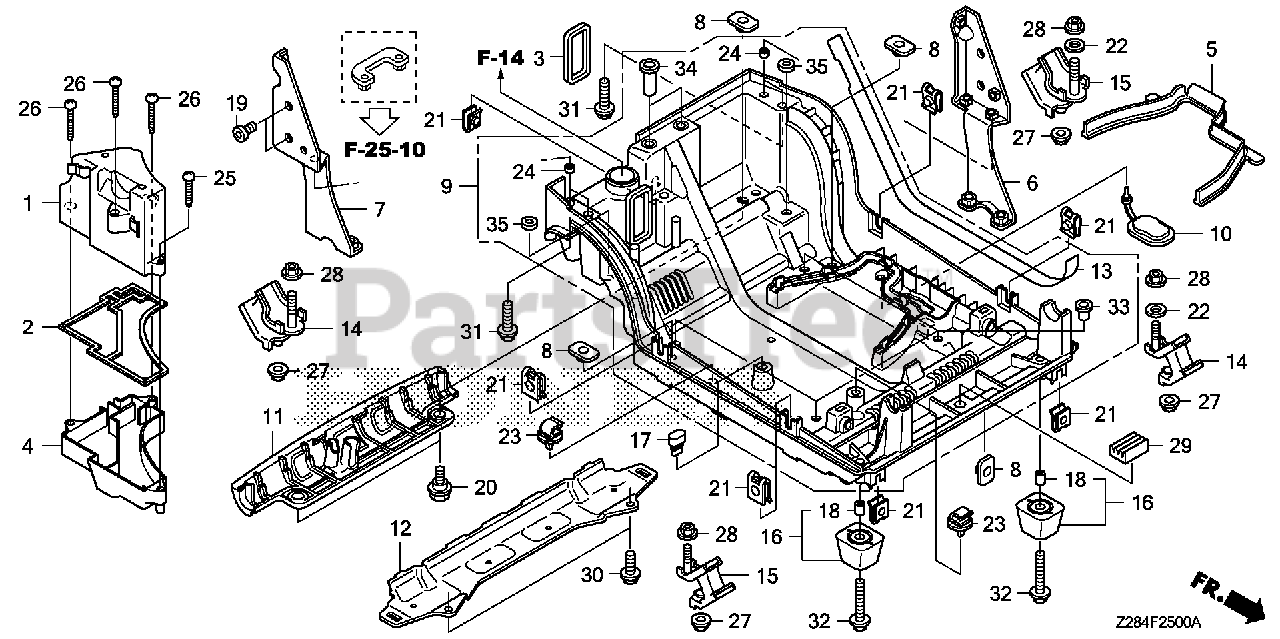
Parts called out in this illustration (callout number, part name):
1	COVER, RESONATOR
2	SEAL A, RESONATOR
3	SEAL B, RESONATOR
4	CASE, RESONATOR
5	GUIDE, AIR (LOWER)
6	PLATE, R. RR. GRIP
7	PLATE, L. RR. GRIP
8	NUT, SPECIAL (6MM)
9	COVER ASSY. (LOWER)
10	PLUG, OIL DRAIN
11	GUARD, RR. (LOWER) *NH314* (CONDUCT GRAY)
12	GUARD, CENTER (LOWER)
13	TAPE, COVER (LOWER)
14	RUBBER, R. FR. MOUNT
15	RUBBER, L. FR. MOUNT
16	RUBBER (LOWER)
17	STOPPER, DISCHARGE GUARD Use up to Frame SN 1186736.
18	COLLAR, RR. FENDER
19	SCREW, PAN (6X12)
20	BOLT, SPECIAL (6MM)
21	NUT, SPRING (6MM)
22	WASHER, PLAIN (8MM)
23	CLIP, HARNESS
24	COLLAR A, COVER (LOWER)
25	SCREW, TAPPING (5X25) (PO)
26	SCREW, TAPPING (5X30)
27	NUT, FLANGE (6MM)
28	NUT, FLANGE (8MM)
29	RUBBER A, STAND STOPPER
30	BOLT, FLANGE (6X10)
31	BOLT, FLANGE (6X14)
32	BOLT, FLANGE (6X20)
33	COLLAR C, COVER (LOWER)
34	COLLAR B, COVER (LOWER)
35	COLLAR D, COVER (LOWER)
